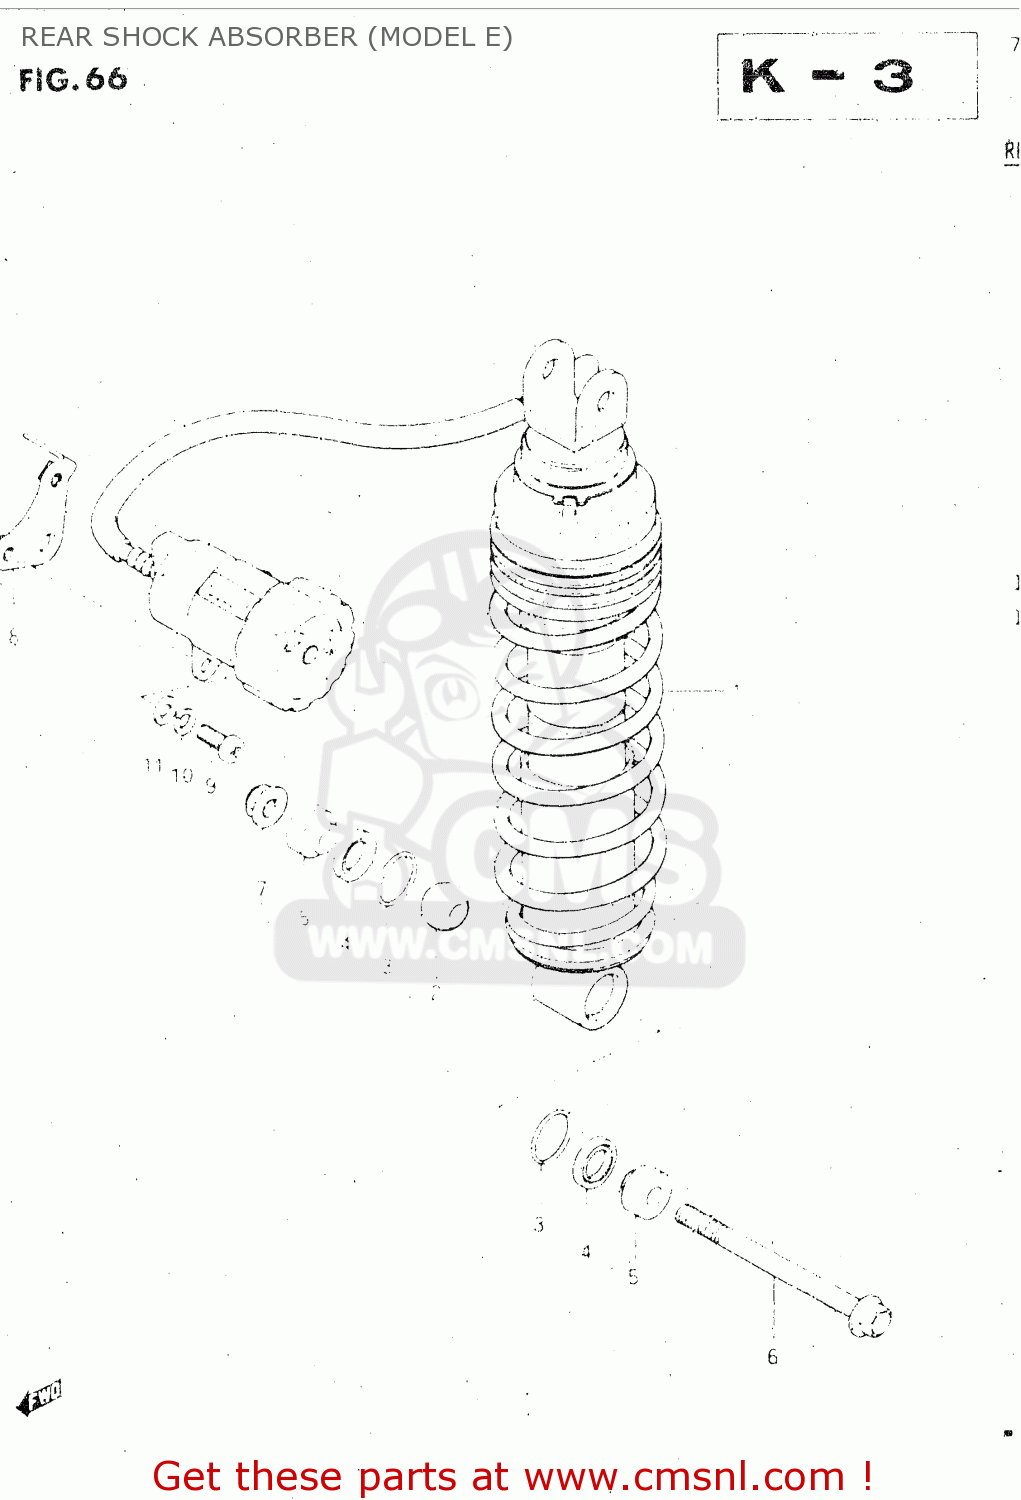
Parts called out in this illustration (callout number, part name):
1	SHOCK ABSORBER ASSY, REAR
2	BEARING(10X24X15)
3	RING
4	SEAL,DUST
5	COLLAR
6	BOLT(10X115)
7	NUT
8	BRACKET,RESERVOIR TANK
9	SCREW
10	LOCK WASHER
11	WASHER
